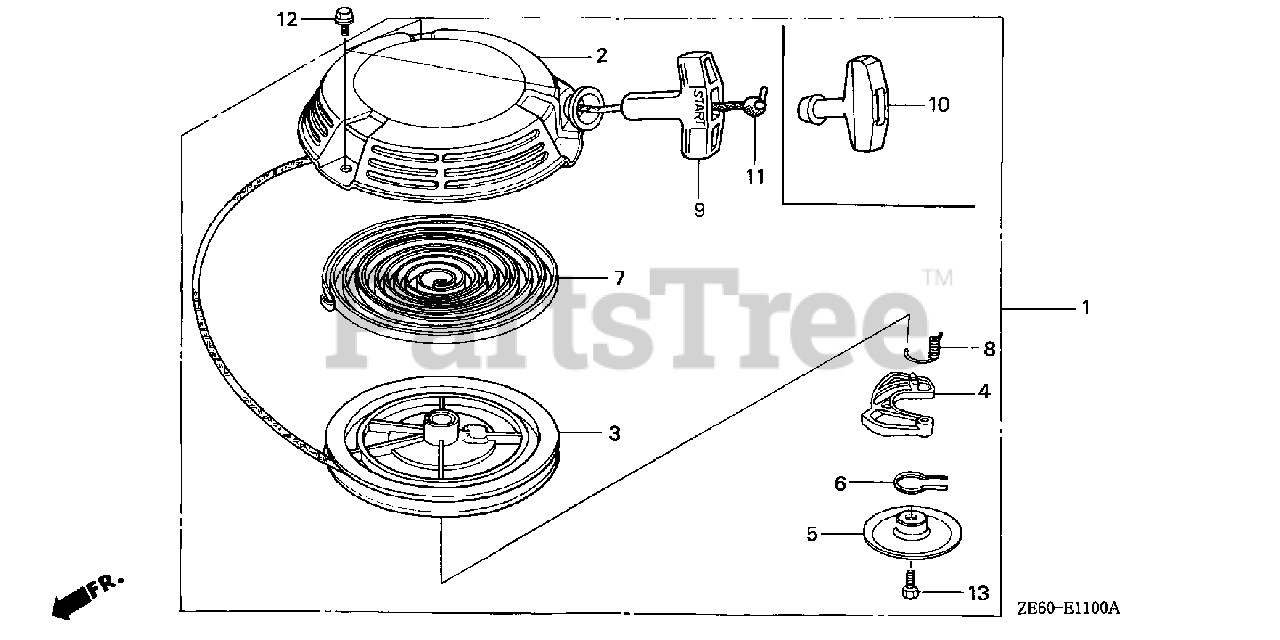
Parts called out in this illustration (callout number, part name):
1	STARTER ASSY., RECOIL *R8* (BRIGHT RED)
1	STARTER ASSY., RECOIL *R280* (POWER RED)
2	CASE, RECOIL STARTER *R8* (BRIGHT RED)
2	CASE, RECOIL STARTER *R280* (POWER RED)
3	PULLEY, RECOIL STARTER
4	RATCHET, STARTER
5	PLATE, FRICTION
6	SPRING, FRICTION
7	SPRING, RECOIL STARTER
8	SPRING, RETURN
9	KNOB, RECOIL STARTER
11	ROPE, LONG (91")
12	BOLT, FLANGE (6X8)
13	BOLT, HEX. (6X12)
